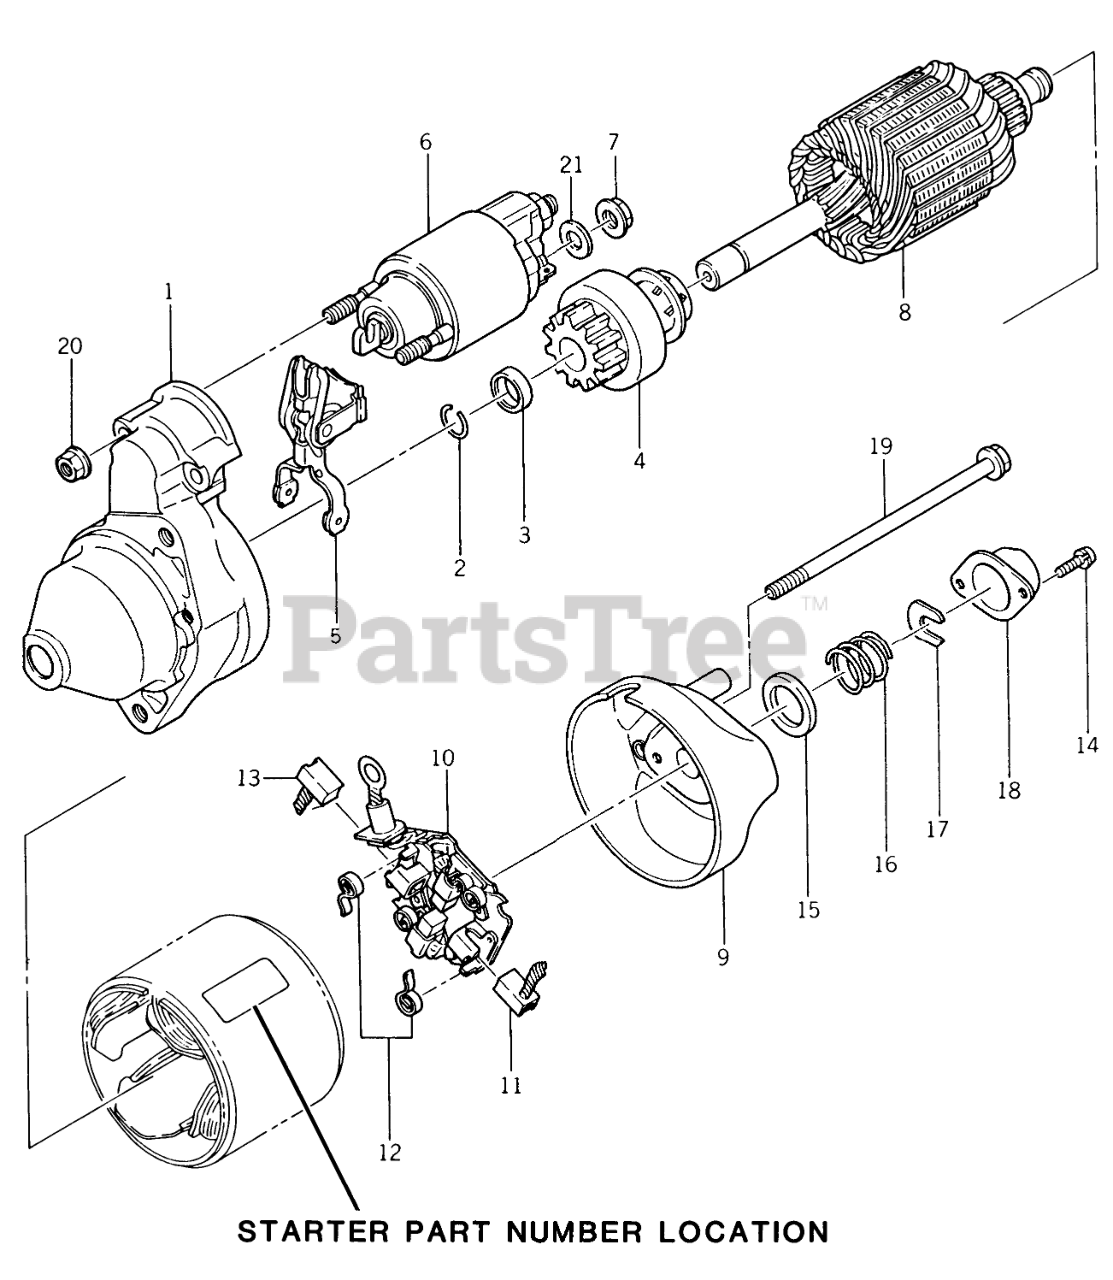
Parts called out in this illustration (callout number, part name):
1	COVER ASS'Y
1	ASS'Y-STARTER COVER
2	RING-SNAP
3	STOPPER PINION
4	CLUTCH ASS'Y
4	ASS'Y-STARTER CLUTCH
5	LEVER SHIFT
5	ASS'Y-SHIFT LEVER
6	SWITCH ASS'Y
6	ASS'Y-STARTER SWITCH
8	ARMATURE
9	COVER ASS'Y
10	BRUSH HOLDER ASS'Y
11	BRUSH
12	Spring
13	BRUSH
14	SCREW
16	SPRING
17	STOPPER
18	COVER
21	Washer
